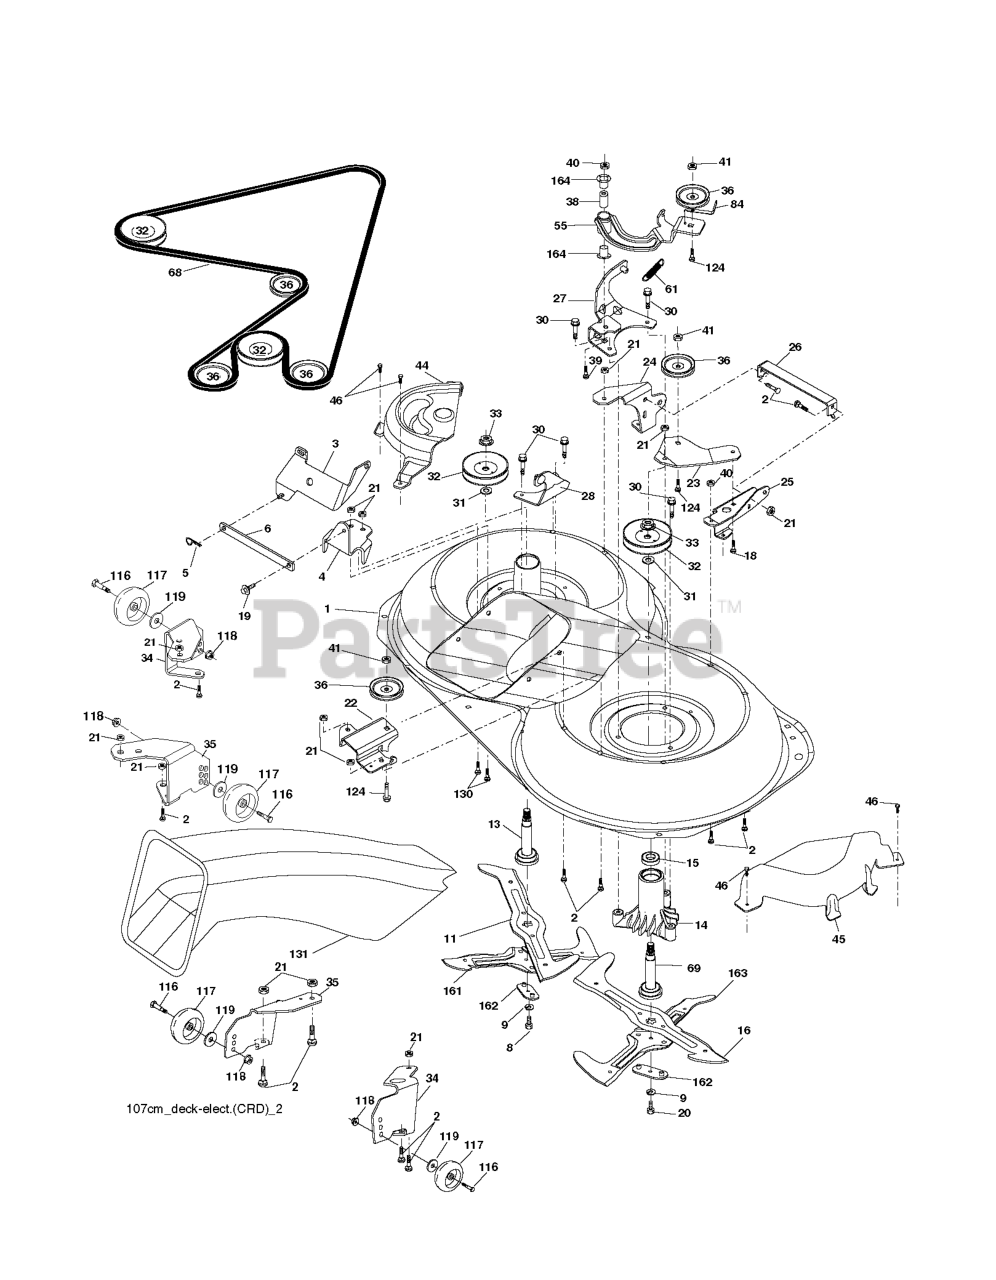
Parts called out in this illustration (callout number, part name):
1	Housing Asm. Mower 107 CRD
2	RP BOLT 5/16-18 X3/4 ZN/YEL GR
5	RETAINER-SPRNG RB
6	BAR.SWAY.92.CRD
8	BOLT.3/8-24X1.25 GR8
9	LOCKWASHER
11	BLADE.3N1.LH.CRD
13	SHAFT ASM VENT
14	HOUSING.MANDREL.VENTED (MACHD)
16	BLADE.3N1.RH.CRD
19	BOLT SHD 5/16-18
20	BOLT.3/8-24X1.25GR8. LHTHRD
21	LOCKNUT
22	BRACKET.IDLER.RR.107.CRD
25	BRACKET RF
26	SUPPORT
28	BRACKET
30	SCREW, WASHER HEAD
31	WASHER.SPACER.MANDREL
32	PULLEY.MANDREL.4.80 PD.2006
33	NUT.FLANGE.LOCK.TOP
34	BRACKET
35	BRACKET
36	PULLEY.IDLER.4.25
41	NUT LOCK FLG 3/8-16 UNC
45	COVER.MANDREL.RH.CRD
46	SCREW.1/4-20X5/8
55	ARM.IDLER.107.CRD
61	SPRING
68	HEX-BELT 107 MOWER
69	SHAFT.ASM.W/LWR.BRG.RH.THREAD
84	KEEPER, BELT IDLER
116	BOLT.SHOULDER.3/8-16X3-5/8.
117	RP WHEEL. GUAGE RALLY
118	LOCKNUT
119	WASHER
124	BOLT.3/8-16X1.50
130	BOLT.CARR.SQNK.5/16-18UNC.X3/4
131	CHUTE BAGGER
163	BLADE.CROSS.RH.CRD.107
164	BRNG T
